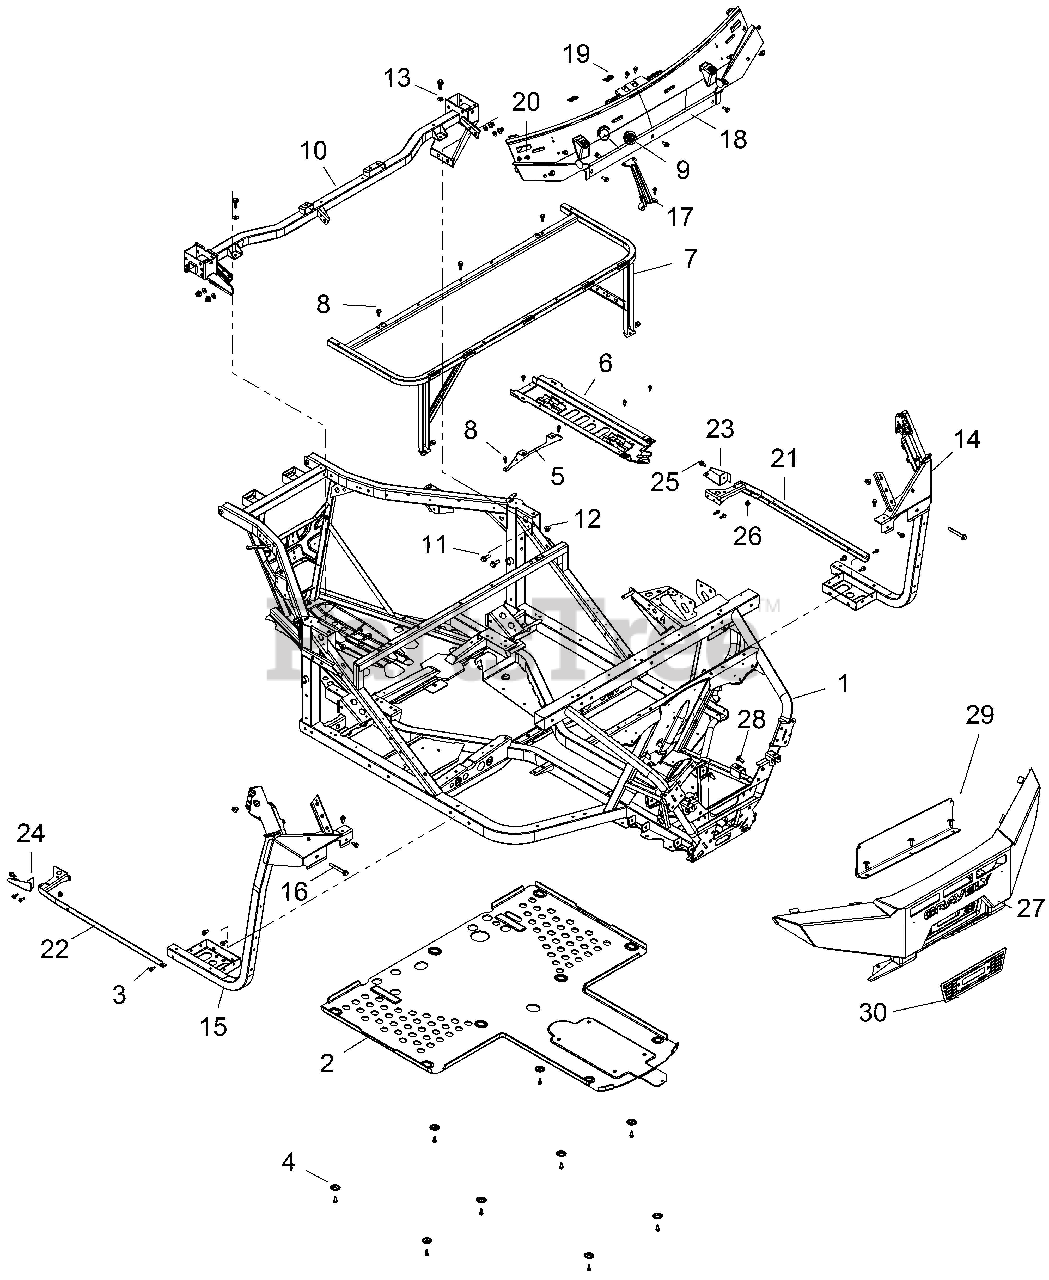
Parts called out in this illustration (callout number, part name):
1	WELD-FRAME,ARIENS GAS,BLK
2	PLATE-SKID,BLK
3	SCR-M6X1.0X20,HXHD,FLG,TDFM,BL
4	WASHER SKID PLATE
5	BRKT-ROUTING TRAY,BLK
6	TRAY-ROUTING,BLK
7	WELD-CAB/SEAT BASE,BLK
8	BOLT-M8X1.25X20,HXFLG,TAP/R-OD
9	GROMMET-ELEC,CAB,SLIT
10	WELD-CAB SUPPORT,REAR,BLK
11	SCR-HXFL-M10X1.25X30 8.8 ZOD
12	NUT-M10X1.25,FLG,NYLOC-OLIVE D
13	WASHER,3/8 FW
14	WELD-FLOOR SUPPORT,LH,BLK
15	WELD-FLOOR SUPPORT,RH,BLK
16	SCR-HXFL-M10X1.25X80 8.8 ZOD
17	BRKT-PLATE,CTR,PIN MT,TTN
18	PLATE,WINDSHIELD MOUNT,LOW BLK
19	CLIP-U SPEED NUT
20	RIVET-TUFLOK,.315-.325X.787 (5
21	WELD-ROCKER,LH,BLK
22	WELD-ROCKER,RH,BLK
23	BRACKET,SUPPORT,ROCKER,LH BLCK
24	BRACKET,SUPPORT,ROCKER,RH BLCK
25	SCR-TXTH-M6X1.0X25 RIE
26	NUT-M8X1.25,HXFLG,NYLON INS
27	WELD-BUMPER,FRONT,ARIENS,M BLK
28	SCR-RHCAR-M10X1.5X25 8.8 ZOD
29	PLATE,GRAVELY RED
30	SCREEN-BUMPER,BLK
